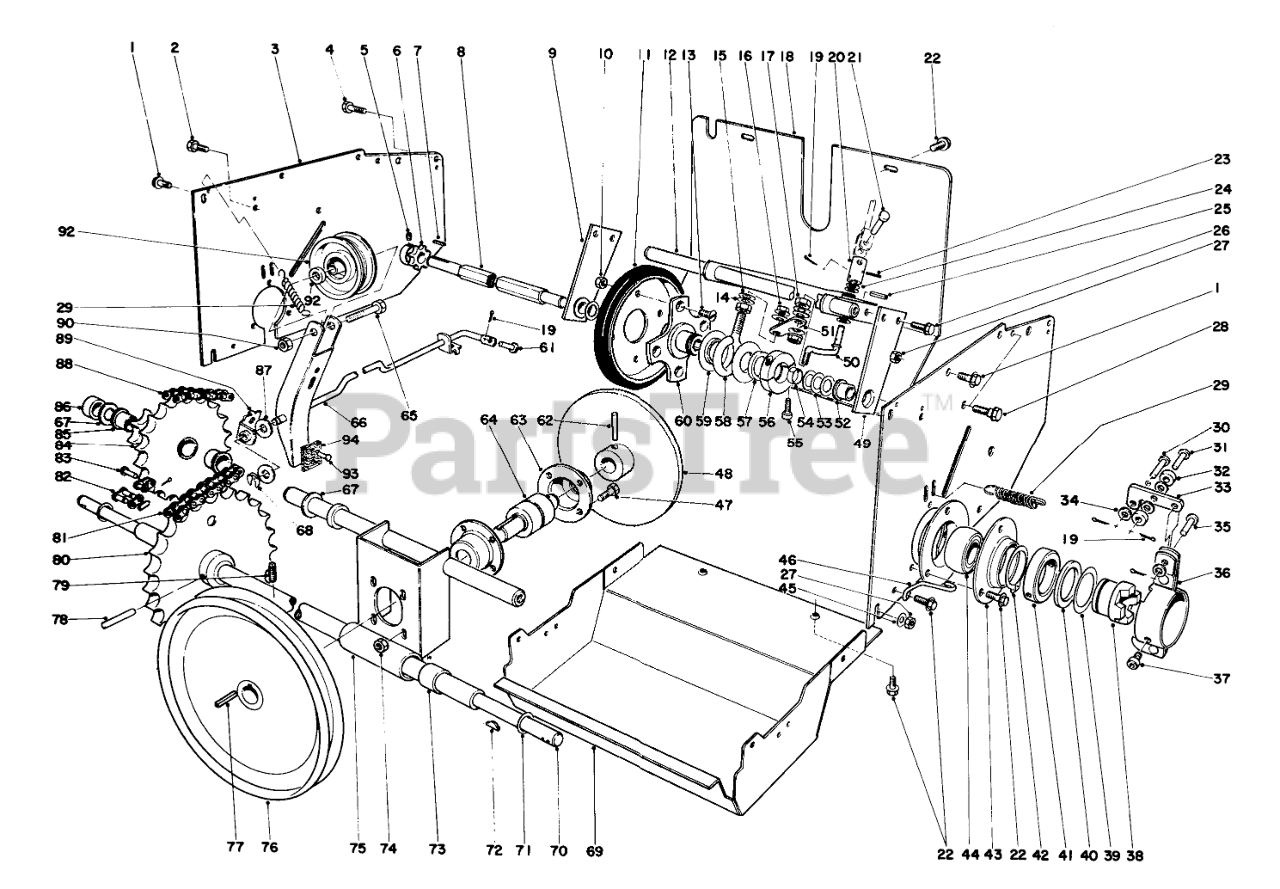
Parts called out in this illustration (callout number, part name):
1	SCREW-HHF
2	SCREW-HWH,THD ROLL
3	Drive Side Plate
4	SCREW-HH, TAP
5	SCREW-HSH
6	SPROCKET
8	FRICTION WHEEL SHAFT
9	Hex Shaft Mount R.H. (Incl. Ref. 52)
10	Nut
11	Disc
12	Bracket Dead Shaft
13	5/16-18X5/8 FLT HD MS
14	WASHER-SPRING
15	WASHER-FLAT
16	NUT-LOCK, FLANGE
17	Nut
18	REAR COVER R
19	PIN-COTTER
20	U JOINT TUBE
21	CLEVIS PIN
22	SCREW-HWH
23	PIN-SPRING
24	Spacer
25	PIN-ROLL
26	SCREW-HWHTF
27	NUT-HEX
28	SHOULDER SCREW
29	EXTENSION SPRING
30	PIN-CLEVIS
31	PIN-CLEVIS
32	CLUTCH ROLLER
33	CLUTCH CAM ARM
34	WASHER-FLAT
35	PIN-CLEVIS
36	CLUTCH MT BRKT ASM
37	SCREW-HSH
38	Clutch Wheel
39	THRUST WASHER
40	THRUST BEARING
41	CLUTCH MOUNT COLLAR
42	RING-RETAINING, EXTERNAL
43	BEARING FLANGE
44	BEARING
45	WASHER-FLAT
46	Clutch Retainer
47	SCREW-HH
48	FRICTION PLT WA
49	Hex Shaft Mount L.H.(Incl.Ref. 52)
50	CONNECTION ROD
51	SHIFT ROD PIVOT
52	BUSHING
53	WASHER-FLAT
54	SPLIT SPACER
55	SCREW-HSH
56	ColIar
57	WASHER-THRUST
58	SLIDER RING COLLAR
59	SLIDER RING
60	TRACTION DISC HUB
61	PIN-CLEVIS
62	PIN-GROOVED
63	HOUSING BEARING
64	Friction Plate Shaft
65	SCREW-HH
66	Auger Idler & Brake Ass-y (Incl. Ref. 93-94)
67	WASHER-THRUST
68	RING-CLIP
69	LOWER SHIELD R
70	Axle Shaft
71	WASHER
72	1/4X1-1/16 HI-PRO KEY
73	BUSHING
74	NUT-KEPS
75	Bulkhead (Incl. Ref. 73)
76	Pulley
78	PIN-GROOVED
79	SCREW-SET, SQH
80	Sprocket
81	Chain Lower
82	LINK-CONNECTING
83	1/4 OFFSET LINK
84	Sprocket (Incl. Ref. 85)
85	3/4ID X 3/4LG BSHG
86	Idler Spacer
87	WASHER-FLAT
88	1/4 X 42 CHAIN W/LINK
89	Bracket-Clutch
90	NUT-HEX
91	Spacer
92	PULLEY-IDLER
93	.185 DIA X .375 RT +
94	BRAKE PAD
